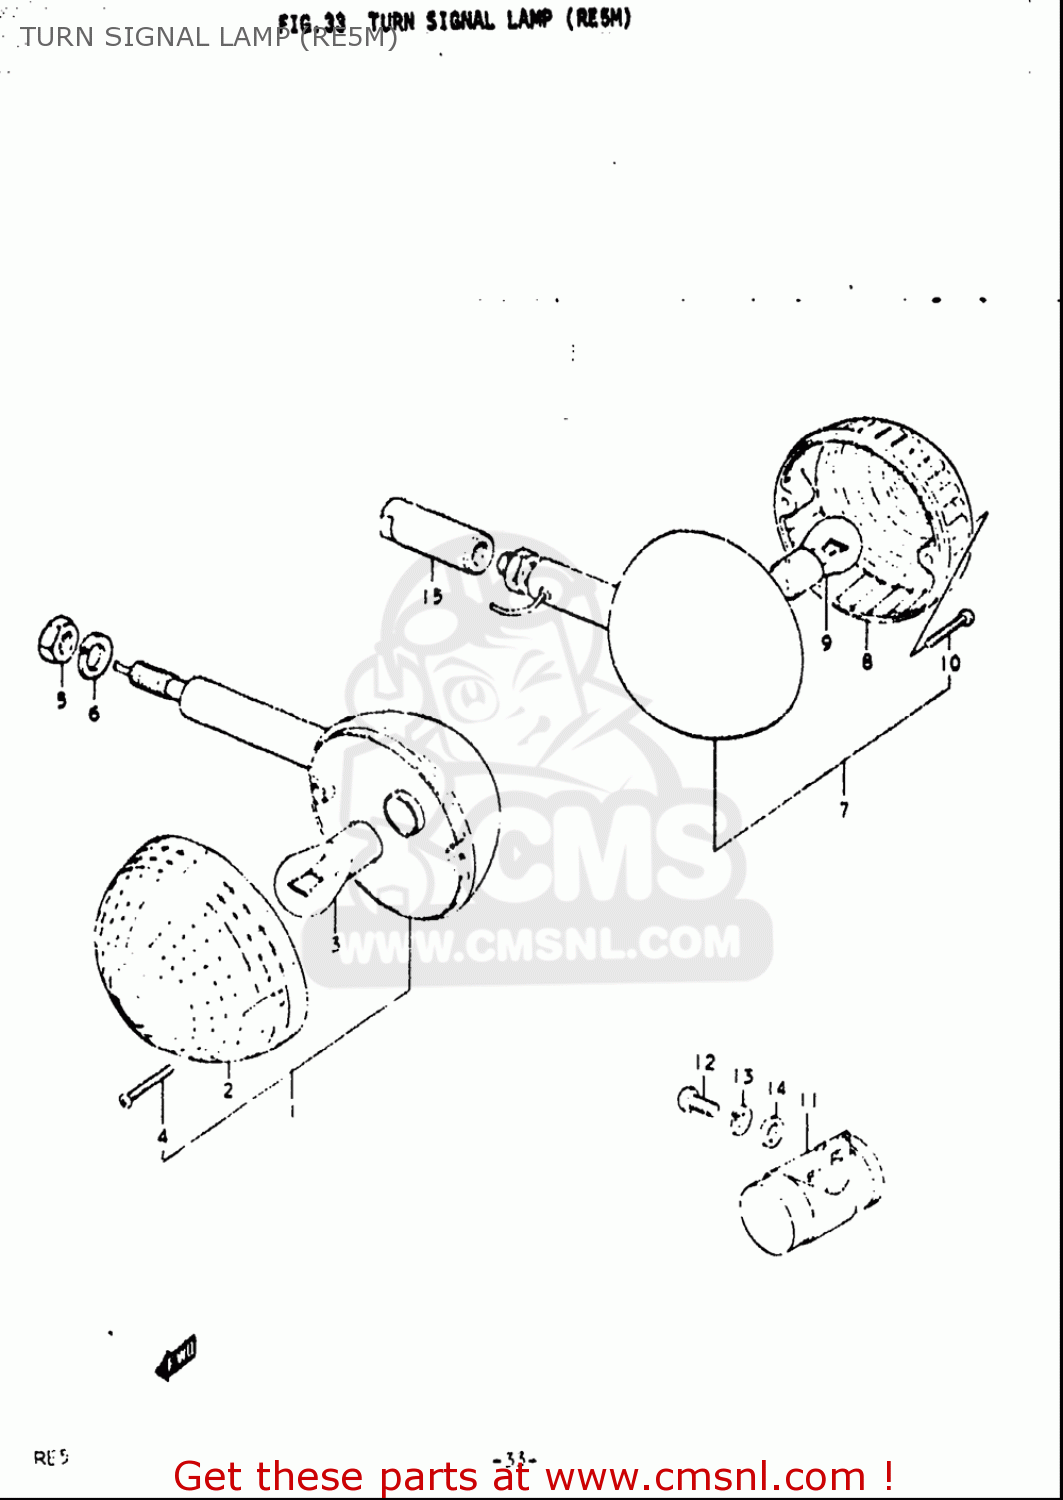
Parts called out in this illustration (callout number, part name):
3	BULB(12V23W,STANLEY,A4577A)
4	SCREW
5	NUT
6	WASHER,LOCK
9	BULB(12V23W,STANLEY,A4577A)
10	SCREW
11	RELAY ASSY,TURNSIGNAL
12	SCREW
13	WASHER,LOCK
14	WASHER
